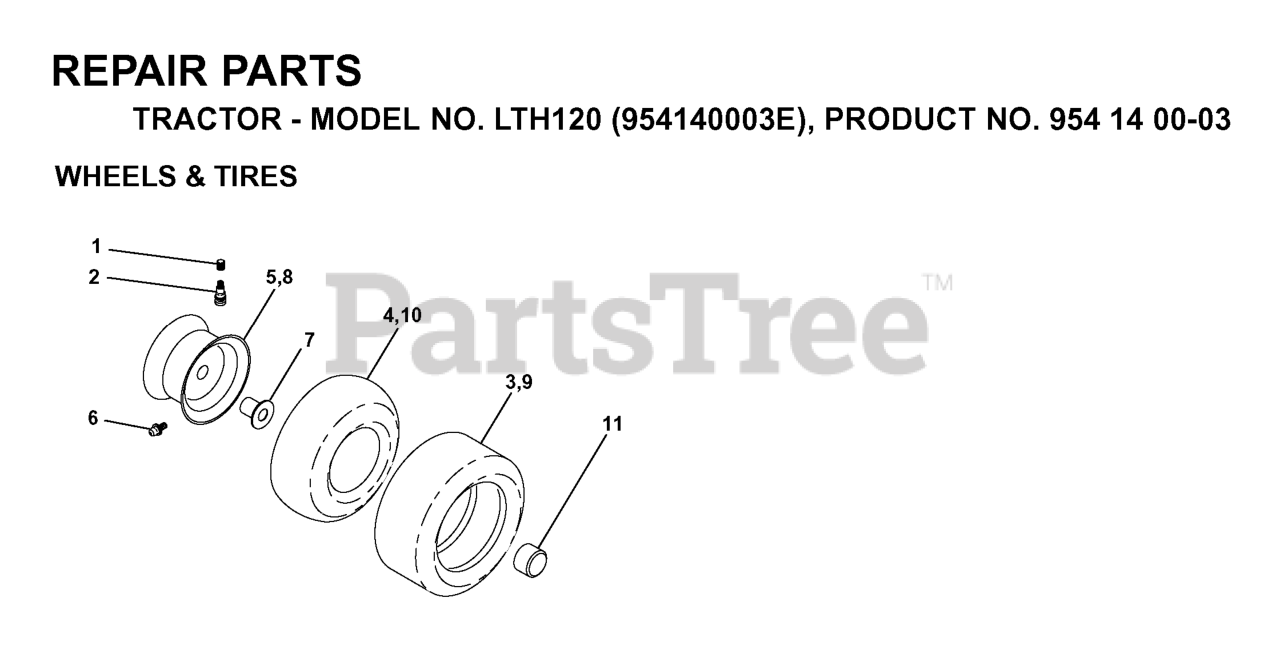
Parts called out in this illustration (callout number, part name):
1	COVER VOLUTE
5	FAN
8	CASE VOLUTE
10	BRACKET DAMPNER
11	CLAMP
14	CLAMP
16	CLAMP
